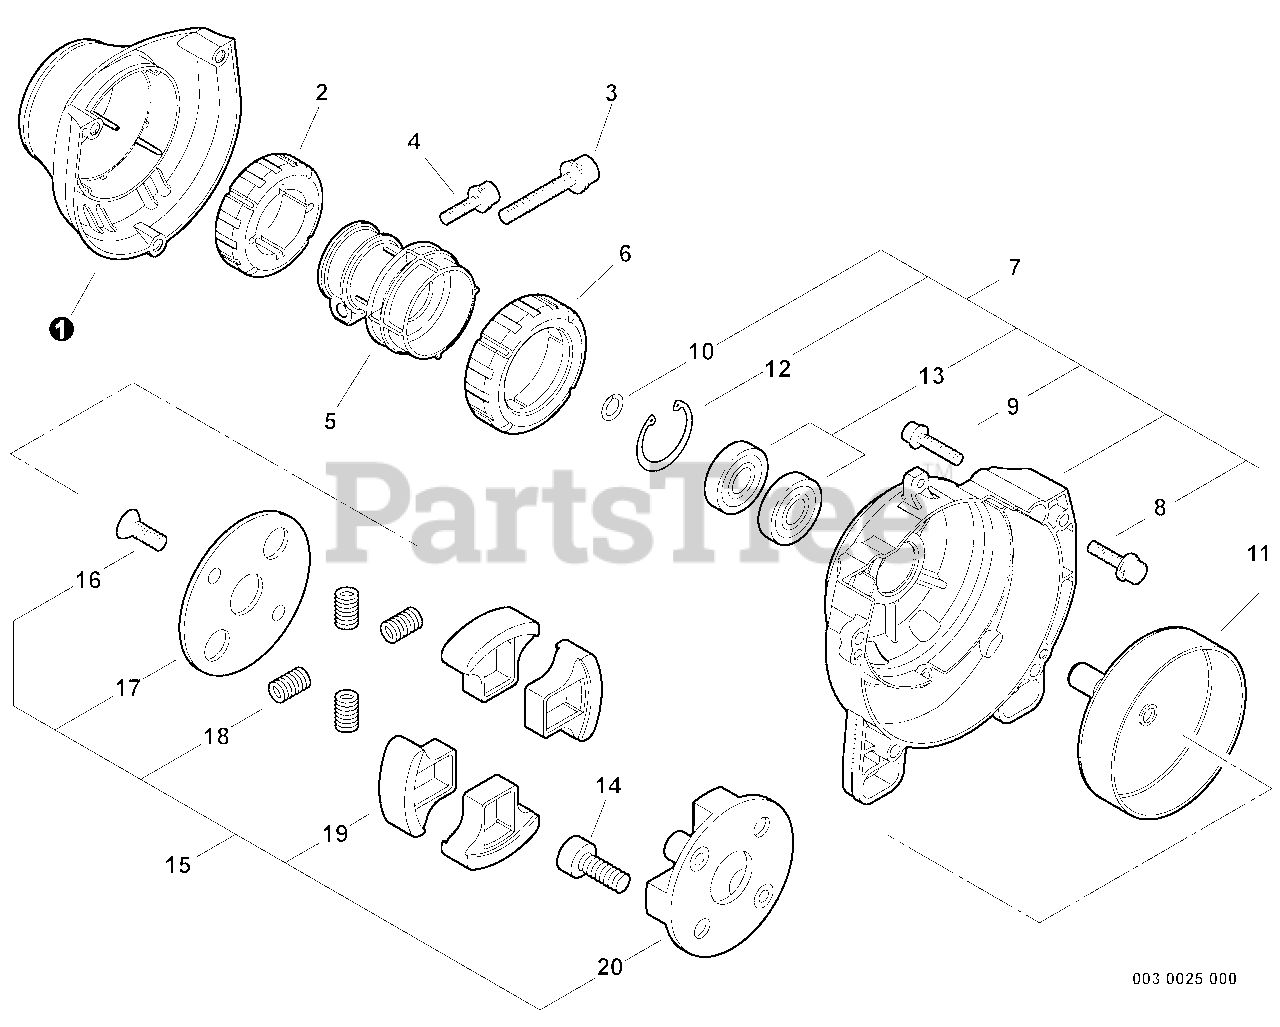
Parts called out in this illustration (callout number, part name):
1	COVER, CUSHION
2	CUSHION - FRONT
3	SCREW - 6X28
4	SCREW - 5X16
5	CLAMP, MAIN PIPE
6	CUSHION - REAR
7	FAN CASE ASSY
8	SCREW - 5X16
9	SCREW - 5X20
10	RING, RETAINING - 12
11	DRUM, CLUTCH
12	RING, RETAINING - 28
13	BEARING, BALL - 6001DDUC3
14	BOLT, CLUTCH
15	CLUTCH ASSY
17	PLATE, CLUTCH
18	SPRING, CLUTCH
19	SHOE, CLUTCH
20	HUB, CLUTCH
